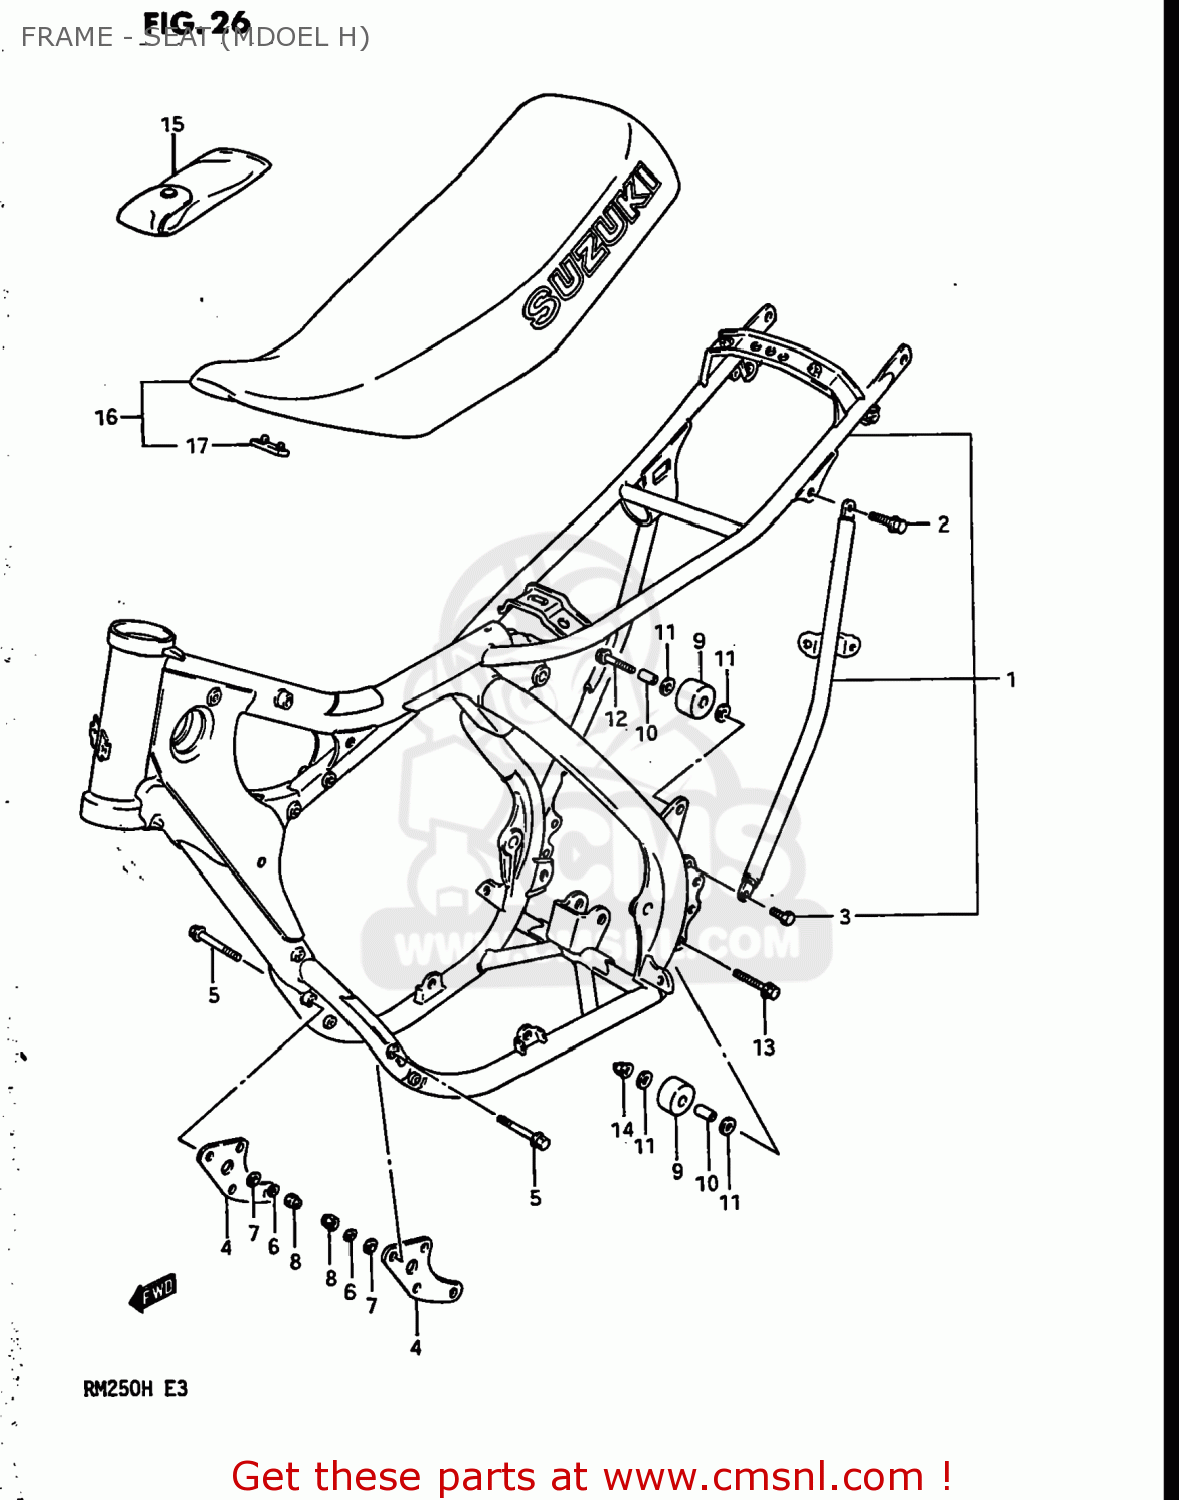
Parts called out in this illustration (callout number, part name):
1	FRAME
2	BOLT
3	BOLT
4	PLATE,ENGINE MOUNTING
5	BOLT 8X55
6	LOCK WASHER
7	WASHER
8	NUT
9	ROLLER,CHAIN CONTROL
10	SPACER (8.6X13.8X28)
11	WASHER
12	BOLT(8X41)
13	BOLT(8X50)
14	NUT
15	TOOL SET
16	SEAT SET
17	CUSHION
